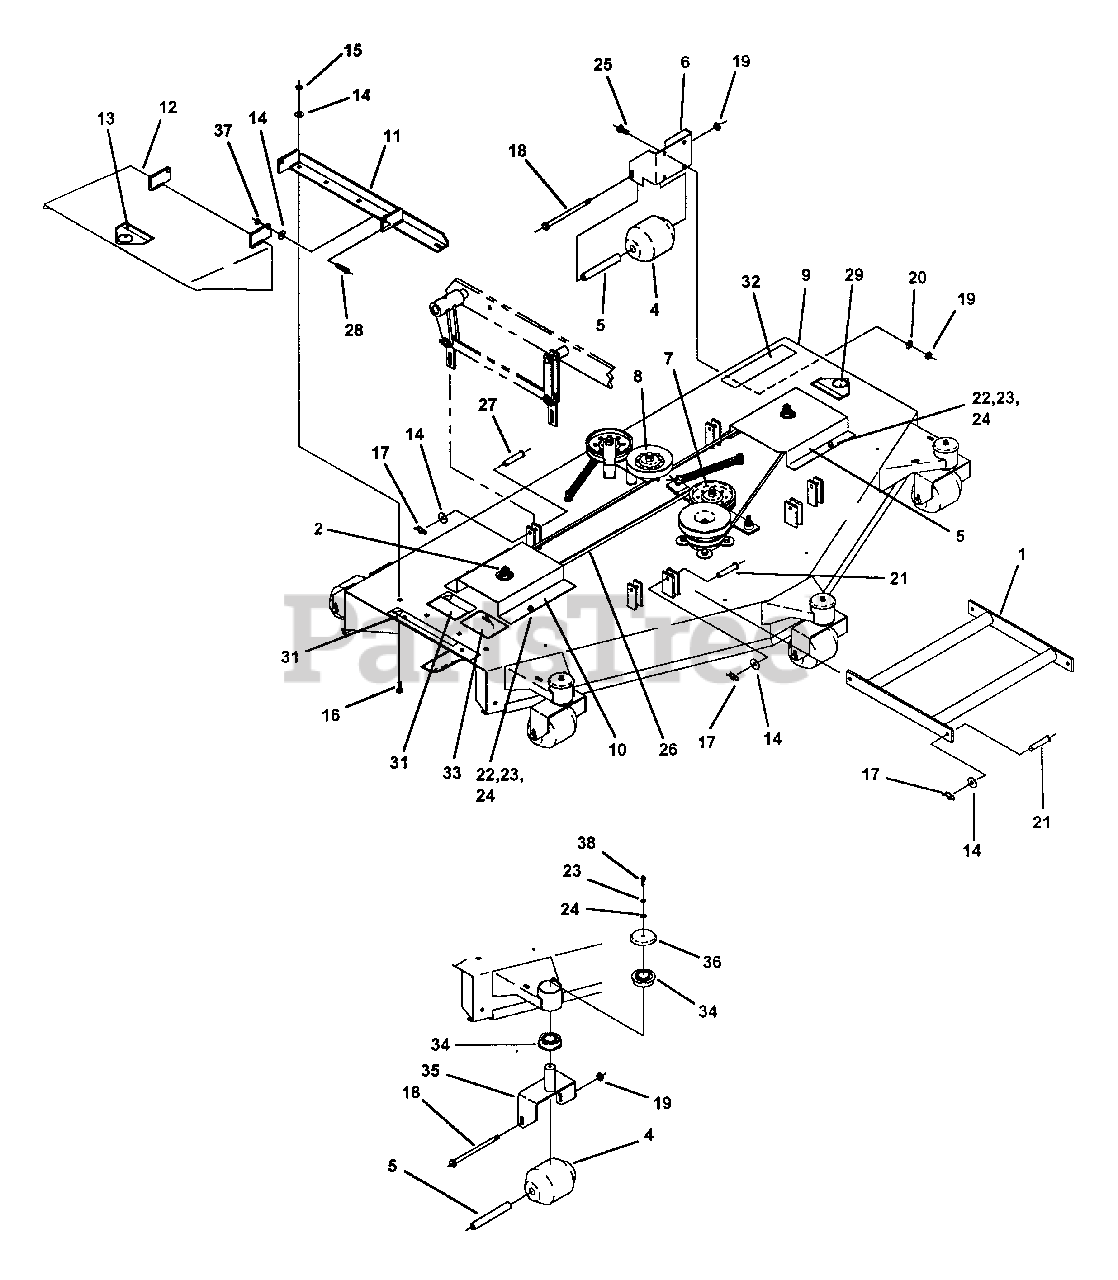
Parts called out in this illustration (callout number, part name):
1	DRAG BAR WELDMENT
2	SPINDLE ASSEMBLY
4	ROLLER, 3-3/4 X 4-13/16" LONG
5	BUSHING
6	BRACKET, REAR CENTER
7	SINGLE IDLER PARTS
8	DOUBLE IDLER ASSEMBLY
9	60" DECK WELDMENT, GEARDRIVE
10	PULLEY COVER, R.H. 60" DECK
11	OUTLET STIFFENER WELDMENT
12	CHUTE WELDMENT (w/decal)
13	DECAL, "BLOODY STUMP"
14	WASHER, FLAT STD. 5/16"
15	NUT, 5/16-18 NYLOC
16	BOLT, 5/16-18 X 3/4" CARRIAGE
17	COTTER RUE RING, 5/16 - 3/8 PIN
18	BOLT, 3/8-16 X 6" GR. 5
19	NUT, 3/8-16 NYLOC
20	WASHER, FLAT STD. 3/8"
21	CLEVIS PIN, 5/16 X 1-1/4" LONG
22	BOLT, 1/4-20 X 3/4" GR. 5
23	LOCKWASHER, 1/4" SPLIT SPRING
24	WASHER, FLAT STD. 1/4"
25	BOLT, 3/8-16 X 7/8" GR. 5
26	DECK CROSS BELT, A-112
27	CLEVIS PIN, 5/16 X 1-1/2" LONG
28	BOLT, 5/16-18 X 1" GR. 5.
29	DECAL, "BLOODY STUMP"
31	DECAL, "MISSING CHUTE"
32	DECAL. "MODEL #Z6004M"
33	DECAL, "GREASE SPINDLES"
34	BEARING, SPD SF-16-32 NO/COLLAR
35	SWIVEL YOKE WELDMENT
36	CAP, BEARING
37	NUT, 5/16-18 STOVER
38	BOLT, 1/4-20 X 3/4" GR. 5 W/NYLON PATCH
